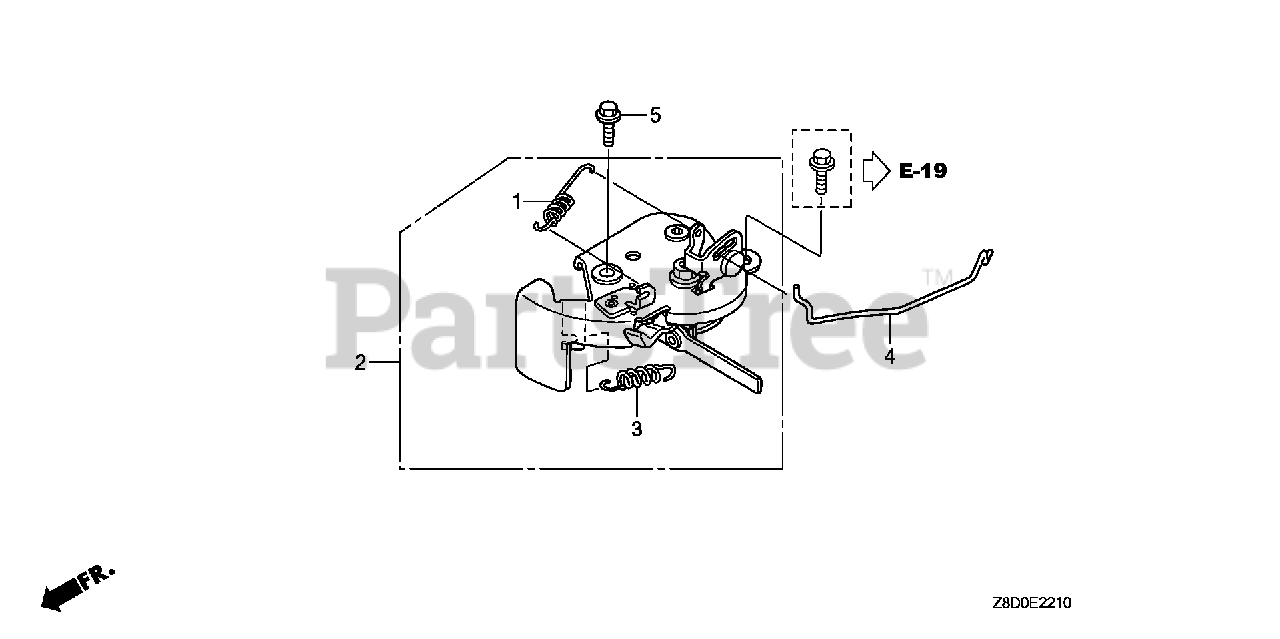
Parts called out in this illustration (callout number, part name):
1	SPRING, RETURN
2	LEVER ASSY., CHOKE
3	SPRING, CHOKE LEVER
5	BOLT, FLANGE (6X20) (CT200)
